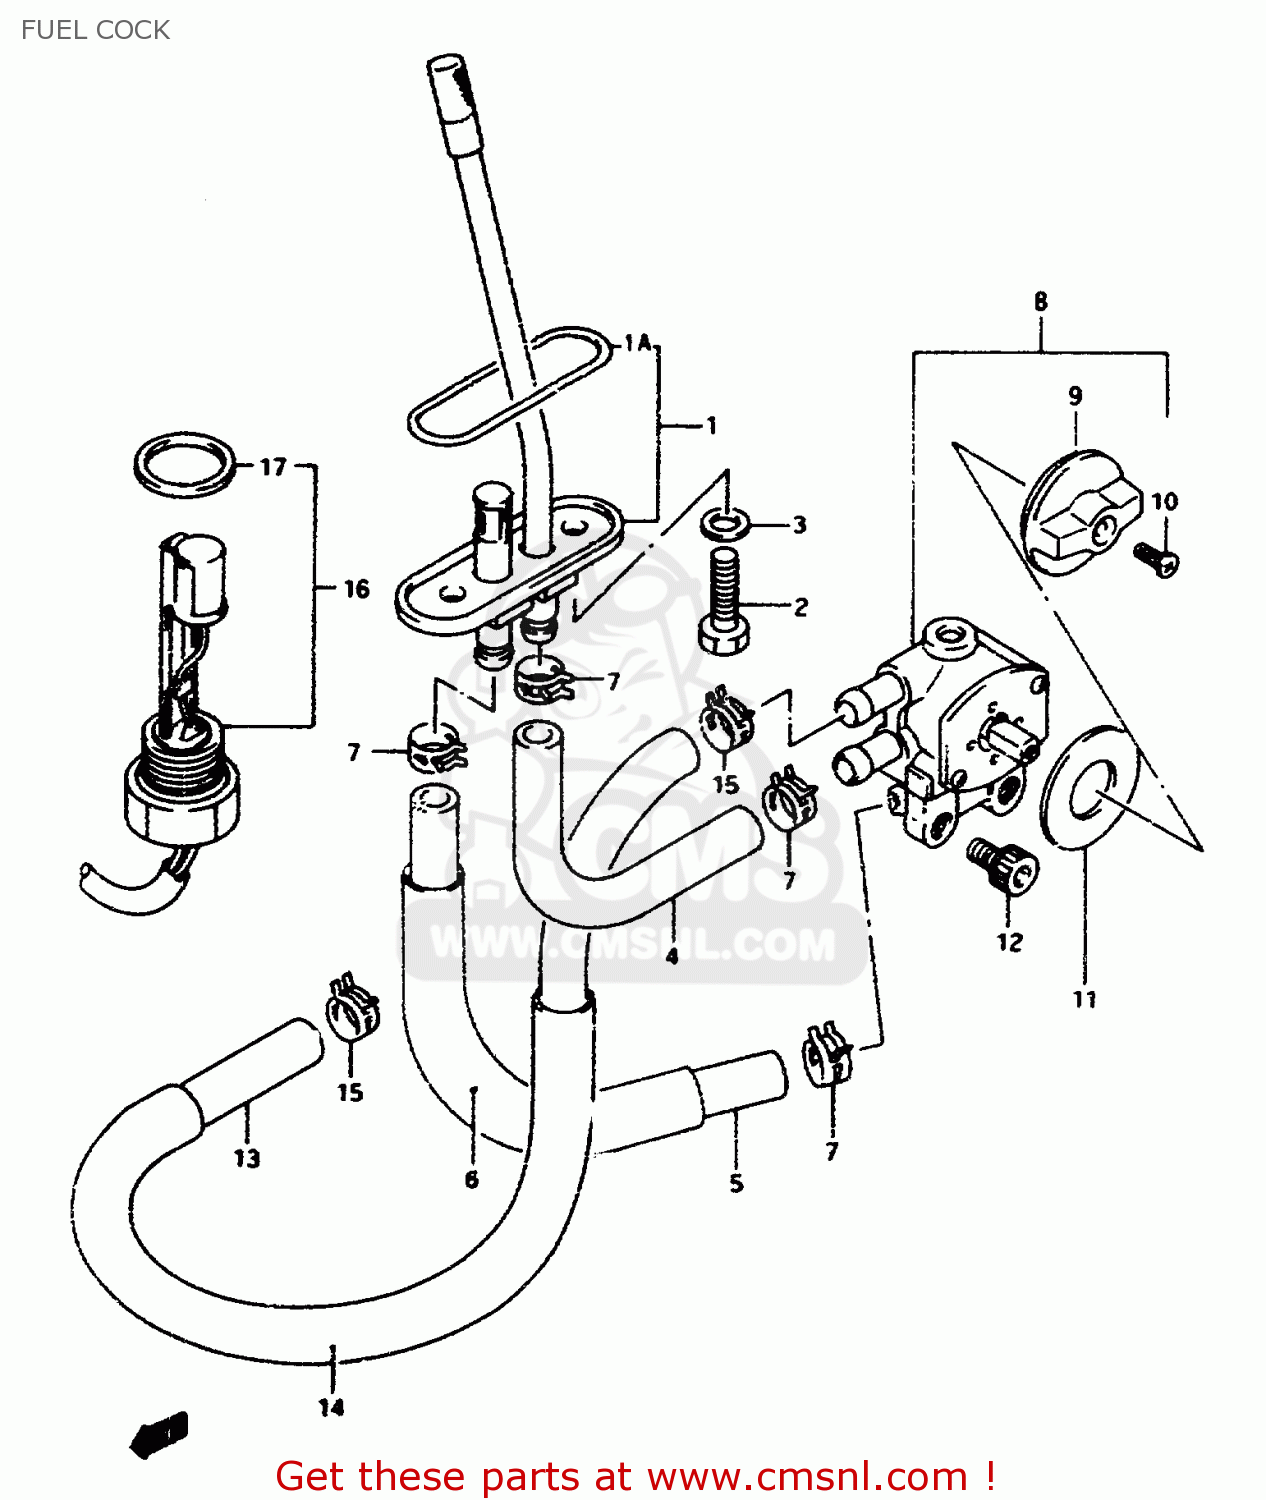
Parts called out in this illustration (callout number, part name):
1	FILTER,FUEL
1A	O RING
2	BOLT(6X20)
3	GASKET(6.4X11.5X0.8) (NAS)
4	HOSE,FUEL ON
5	HOSE(7X12X600)
6	PROTECTOR(14.5X15.5X600)
7	CLIP
8	COCK ASSY,FUEL
9	LEVER,FUEL COCK
10	SCREW,COCK LEVER
11	COVER,FUEL COCK
12	SCREW
13	HOSE(7X12X600)
14	PROTECTOR(14.5X15.5X600)
15	CLIP
16	GAUGE ASSY,FUEL LEVEL
17	GASKET,FUEL LEVEL GAUGE (NAS)
